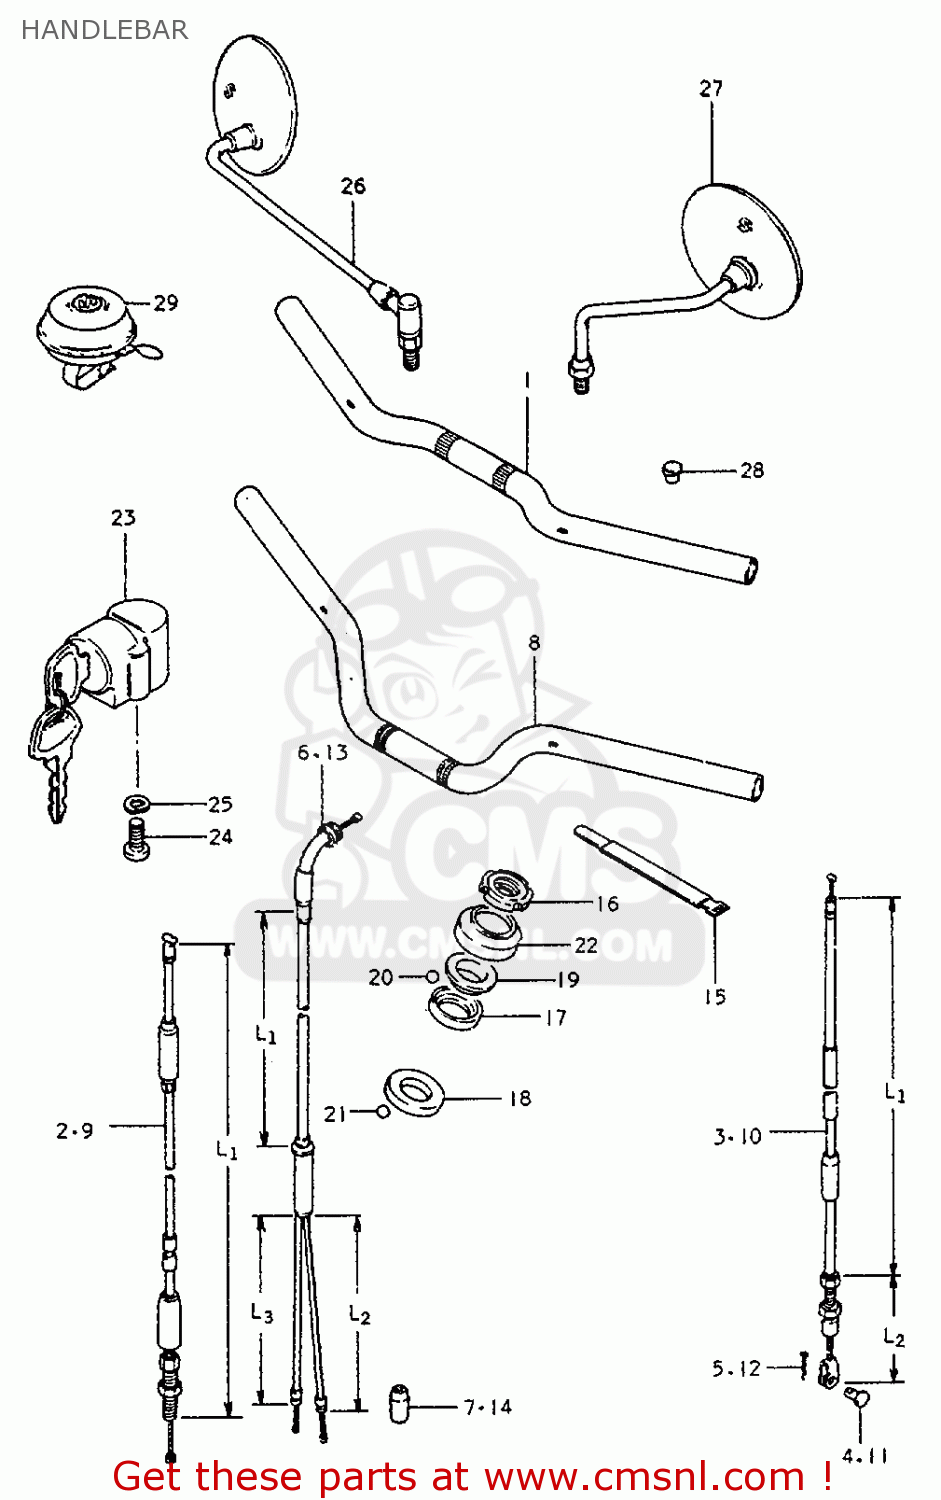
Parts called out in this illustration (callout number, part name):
1	HANDLEBAR FLAT TYPE
2	CABLE, FRONT BRAKE
3	CABLE,CLUTCH
4	PIN(L:13)
5	PIN
6	CABLE, THROTTLE (L1:420,L2:210,L3:310) F
7	SEAL,DUST(7X18X30)
8	HANDLEBAR NEUTRAL TYPE
9	CABLE ASSY,FR BRAKE
10	CABLE ASSY,CLUTCH
11	PIN(L:13)
12	PIN
13	CABLE ASSEMBLY,THROTTLE
14	SEAL,DUST(7X18X30)
15	CLAMP
16	NUT,STEERING STEM(25X44X10)
17	RACE,STEERING INNER UPR
18	LACE,STEERING INNER LWR
19	RACE,STEERING OUTER UPR
20	BALL
21	BALL
22	DUST SEAL,STEERING UPR
23	LOCK ASSEMBLY,STEERING
24	SCREW
25	LOCK WASHER
26	MIRROR ASSY, REAR VIEW
28	CAP
